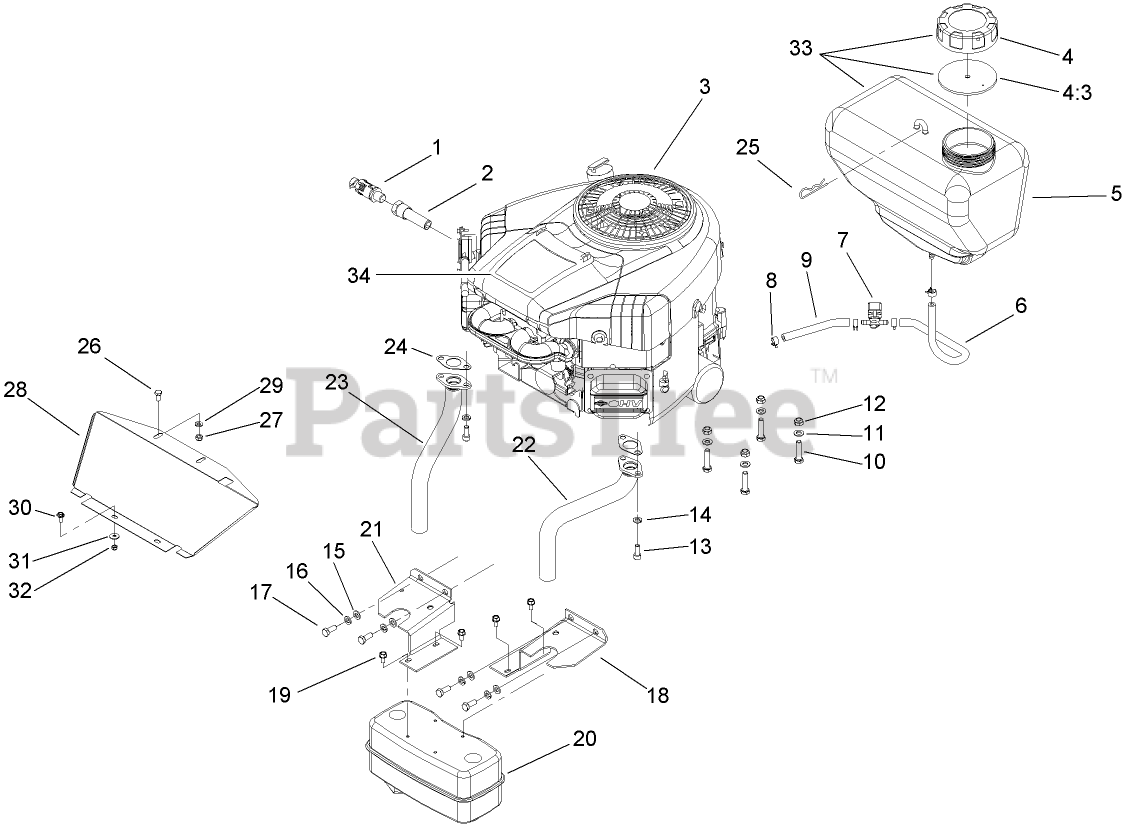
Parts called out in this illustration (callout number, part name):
1	VALVE-OIL DRAIN
2	Coupler-Oil Drain
3	Loose Parts Package
4	GAS CAP ASM
4:3	GASKET-CAP, GAS
5	TANK-FUEL
6	LINE-FUEL
7	VALVE-TANK, FUEL
8	CLAMP-LINE, FUEL
9	LINE-FUEL
10	SCREW-HH
11	WASHER-PLAIN
12	NUT-LOCK, NI
13	WASHER-SPRING
14	SCREW-HH
15	WASHER-PLAIN
16	WASHER-SPRING
17	SCREW-HH
18	GUARD-MUFFLER, LH
20	MUFFLER
21	GUARD-MUFFLER, RH
22	TUBE-EXHAUST, LH
23	TUBE-EXHAUST, RH
24	GASKET-EXHAUST
25	PIN-HAIR
26	SCREW-HH
27	NUT-LOCK
28	SHIELD-HEAT
29	WASHER-FLAT
31	WASHER-FLAT
32	NUT-LOCK
34	DECAL-ENGINE (725CC B&S INTEK)
